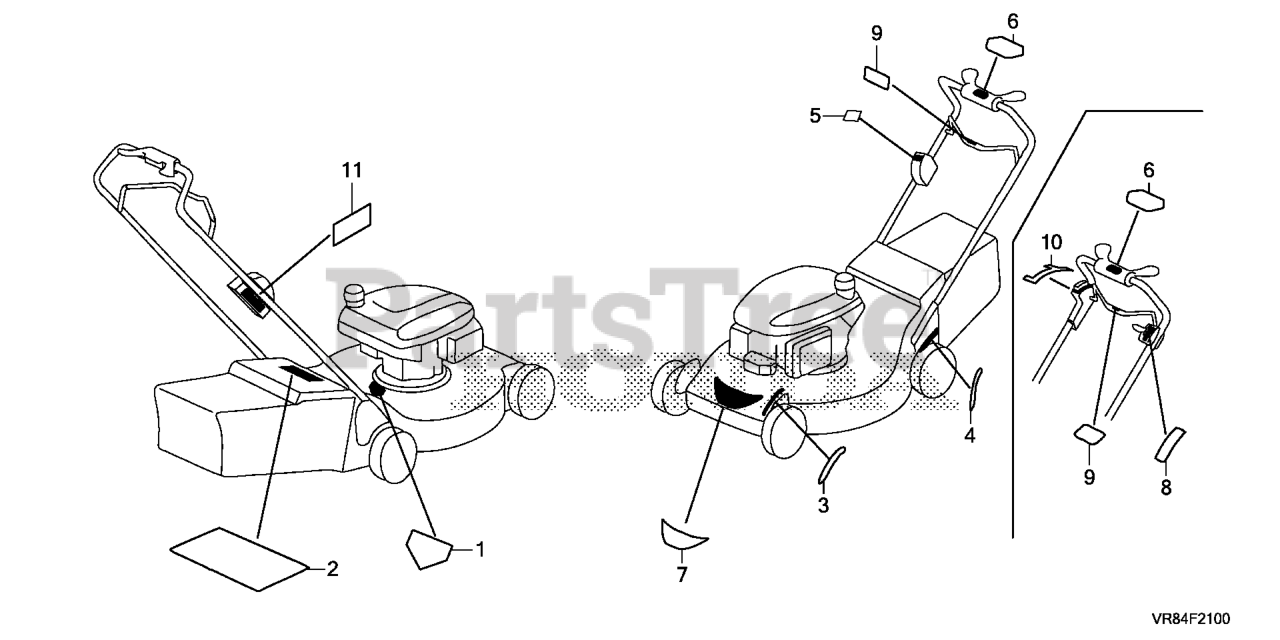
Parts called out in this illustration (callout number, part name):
1	LABEL C, HOUSING CAUTION
2	LABEL, WARNING (ENGLISH)
3	MARK, FR. HEIGHT ADJUSTMENT
4	MARK, RR. HEIGHT ADJUSTMENT
5	MARK, ENGINE SWITCH
6	MARK, CLUTCH INDICATION
7	MARK, HONDA
9	MARK, BLADE CONTROL (ENGLISH)
11	MARK, ELECTRIC STARTER
